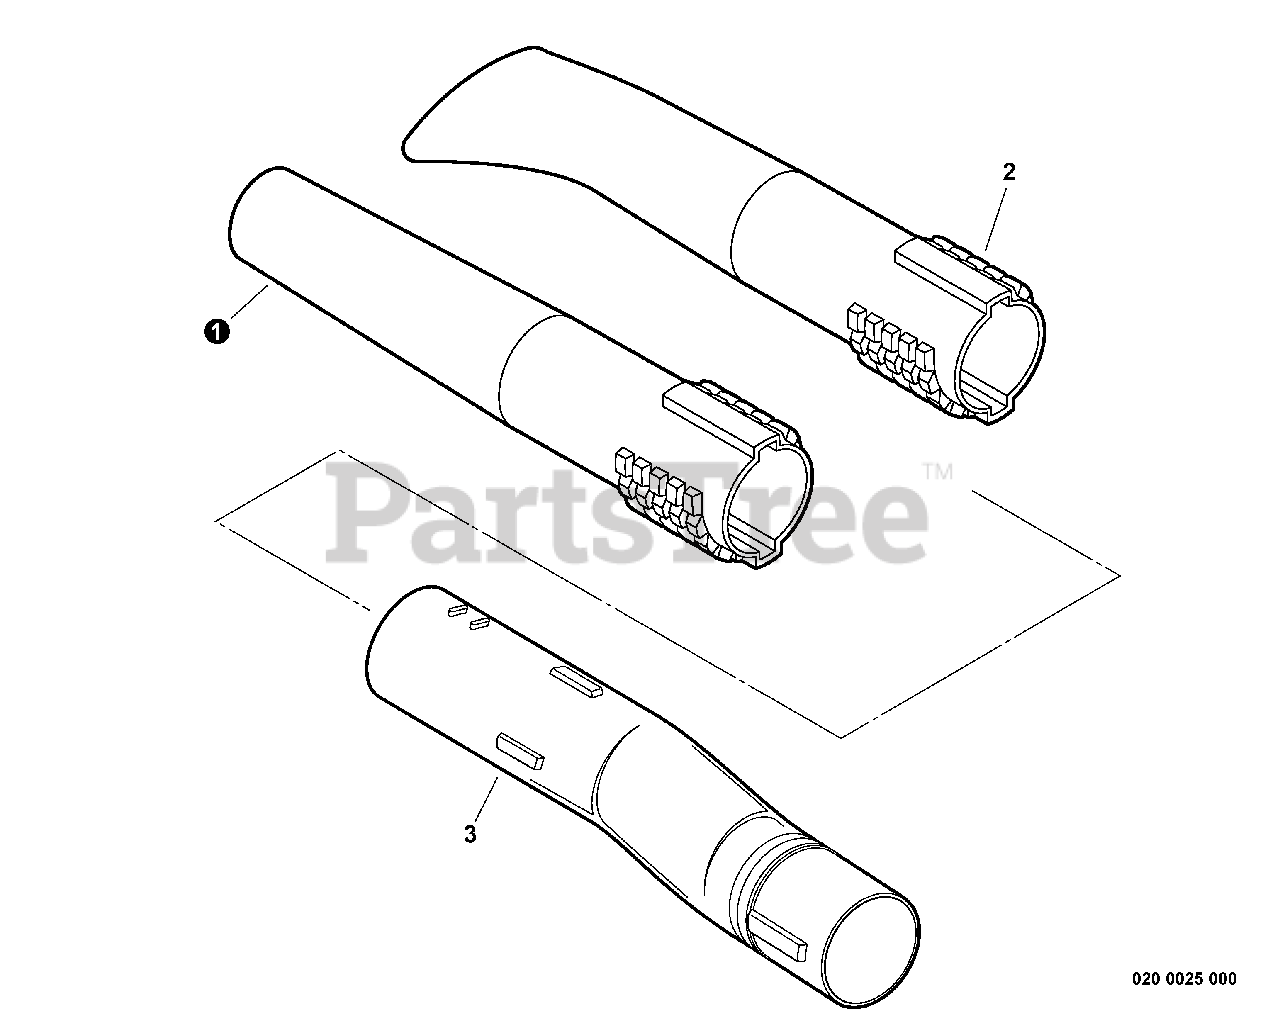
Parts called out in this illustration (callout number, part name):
1	TUBE, BLOWER - ROUND NOZZLE
2	TUBE, BLOWER - FLARED NOZZLE
3	TUBE, BLOWER - CURVED
